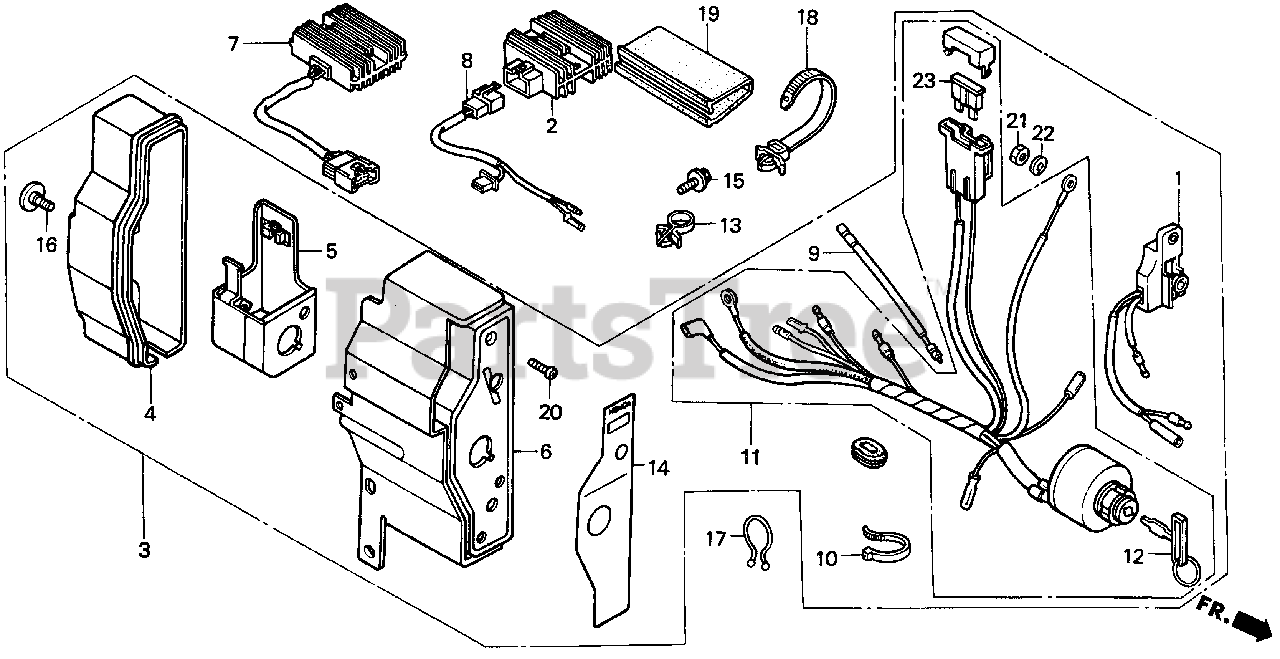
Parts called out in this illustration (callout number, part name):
1	ALERT UNIT, OIL (SEL)
2	RECTIFIER ASSY., REGULATOR
3	BOX ASSY., CONTROL (10A) *R8* (EXTERNAL-ALERT) (BRIGHT RED)
3	BOX ASSY., CONTROL (EXTERNAL-ALERT/10A) *R8* (BRIGHT RED)
4	CASE, CONTROL
5	BRACKET, CASE MOUNTING
6	PANEL, CONTROL *R8* (BRIGHT RED)
8	SUB-WIRE HARNESS ASSY.
10	BAND
11	SWITCH ASSY., COMBINATION
12	KEY
13	HOLDER, STOP SWITCH WIRE
14	MARK, CONTROL BOX (EXTERNAL-REGULATOR)
14	MARK, CONTROL BOX (EXTERNAL-ALERT-REG)
15	BOLT, FLANGE (6X12) (CT200)
16	SCREW, SPECIAL (6X12)
17	CLIP, PURSE LOCK
18	STRAP, CABLE (118MM) *NH1L* (BLACK)
19	TUBE, FASTENER (30)
20	SCREW, PAN (4X12)
21	NUT, HEX. (4MM)
22	WASHER, SPRING (4MM)
23	FUSE, BLADE (15A)
